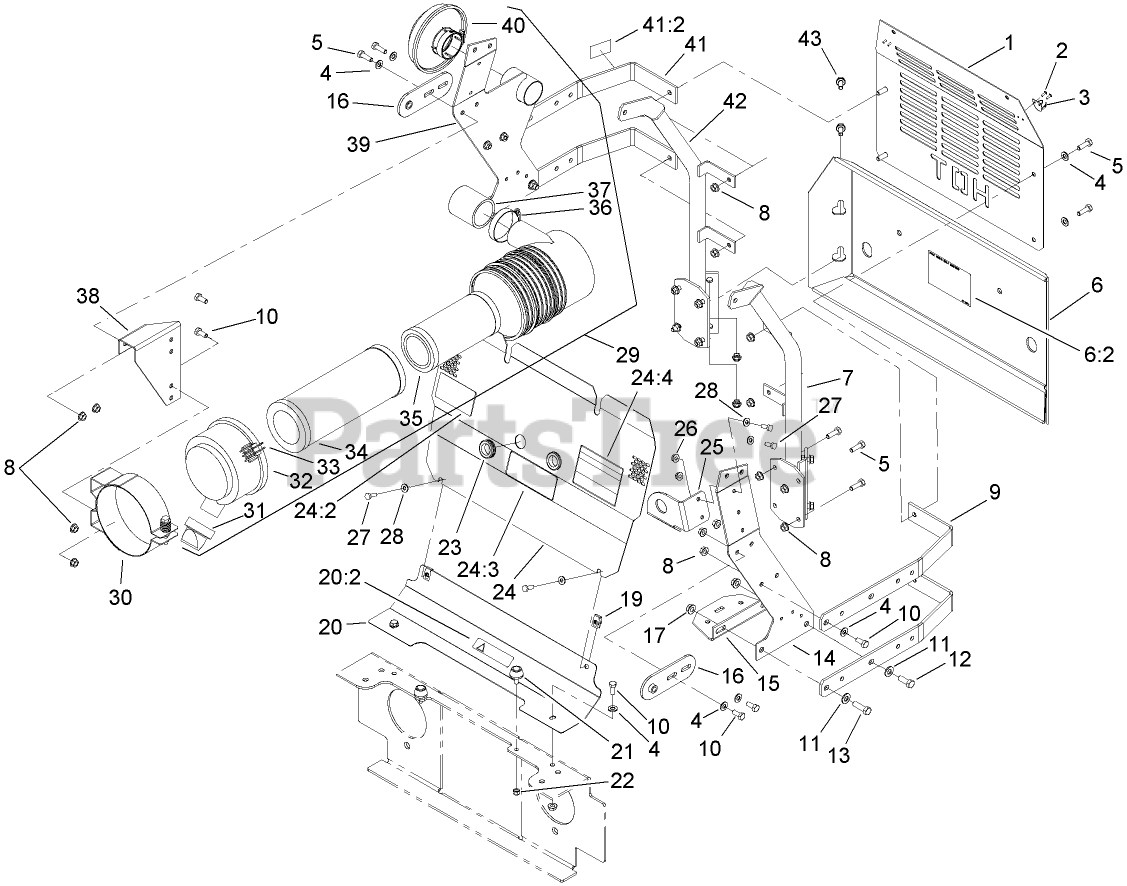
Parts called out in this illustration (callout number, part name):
1	GUARD-MUFFLER
2	RIVET
3	KEEPER-LATCH, RUBBER
4	WASHER-PLAIN
5	SCREW-HH
6	REAR BUMPER ASM
6:2	DECAL-BELT ROUTING, DECK DRIVE
7	FRAME-UPPER, LH REAR
8	NUT-HF
9	BAR-MOUNT FRAME, RADIATOR
10	SCREW-HH
11	WASHER-FLAT
12	SCREW-HH
13	SCREW-HH
14	MOUNT-SIDE, LH
15	BRACKET-BOTTLE
16	SHACKLE-HINGE
17	NUT-HHF, WHIZ
20	SHIELD LOWER ASM
20:2	DECAL-WARNING
21	BUMPER-RUBBER
22	NUT-LOCK, NI
23	GROMMET-RUBBER
24	ENGINE ACCESS PANEL ASM
24:2	DECAL-BELT ROUTING, PUMP
24:3	DECAL-DEVICES, ROTATING
24:4	DECAL-BUZZER, WARNING
25	BRACKET-BUZZER
26	NUT-HF
27	SCREW-HH
28	WASHER-FLAT
29	FILTER-AIR
30	BRACKET-FILTER, AIR
31	VALVE-VACUATOR
32	COVER-FILTER, AIR
33	LATCH-CLEANER, AIR
34	FILTER-AIR
35	FILTER-AIR, SAFETY
36	CLAMP-HOSE
37	HOSE-INTAKE
38	MOUNT-CLEANER, AIR
39	RH RADIATOR AND AC SUPPORT ASM
40	HOOD-CLEANER, 2" AIR INTAKE
41	RADIATOR BAR ASM
41:2	DECAL-SURFACE, HOT
42	FRAME-UPPER, RH REAR
43	SCREW-HHF
